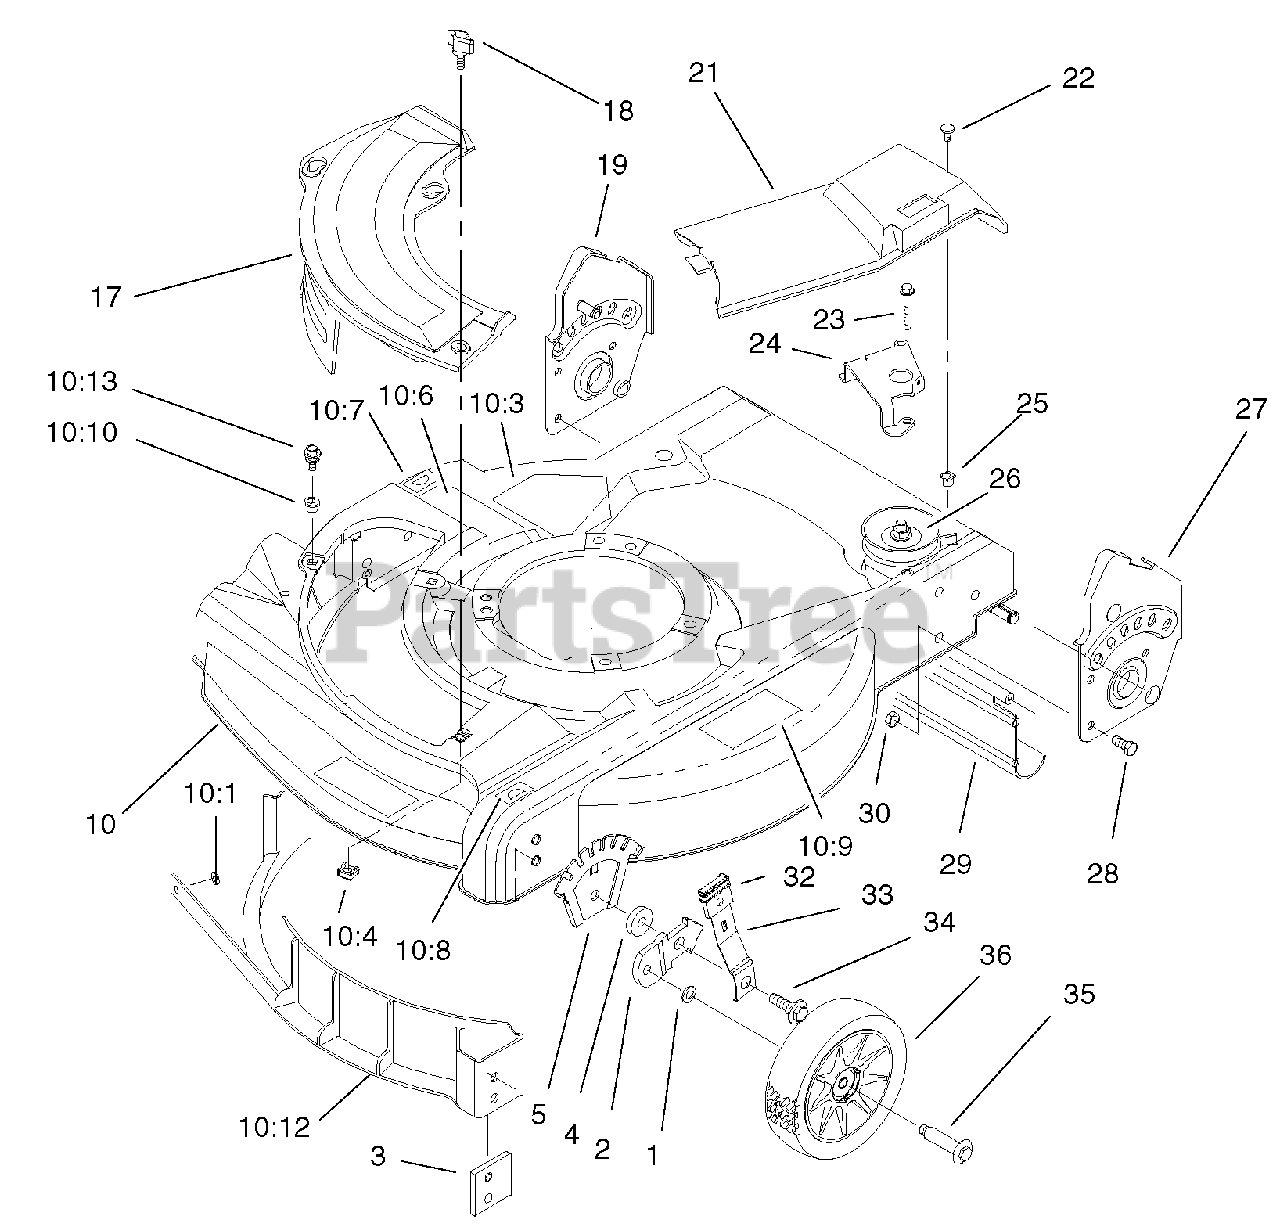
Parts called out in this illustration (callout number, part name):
2	Bracket-Wheel Height Adjustment
3	Plate-Baffle
4	Washer-Wheel
5	Plate-Height Adjustment
10	Deck ASM
10:1	Washer-Flat
10:3	Decal-Danger
10:4	Nut-Cage
10:6	Decal-Warning
10:7	Decal-HOC, RH
10:8	Decal-HOC, LH
10:9	Decal-Warning
10:10	Grommet-Plastic
10:12	Insert-Housing
10:13	Screw-Sems
17	Plate-Mulch
19	Handle Bracket ASM-RH
21	Cover-Drive
23	Screw-HWHTF
24	Guide-Transmission
25	Grommet
26	Gear Case ASM
27	Handle Bracket ASM-LH
28	Screw-HH
29	Shield-Trailing
30	Nut-Lock
32	Knob-Lever, Height Adjustment
33	Arm-Front Spring
34	Bolt-Shoulder
35	Bolt-Shoulder
36	Wheel & Tire ASM
